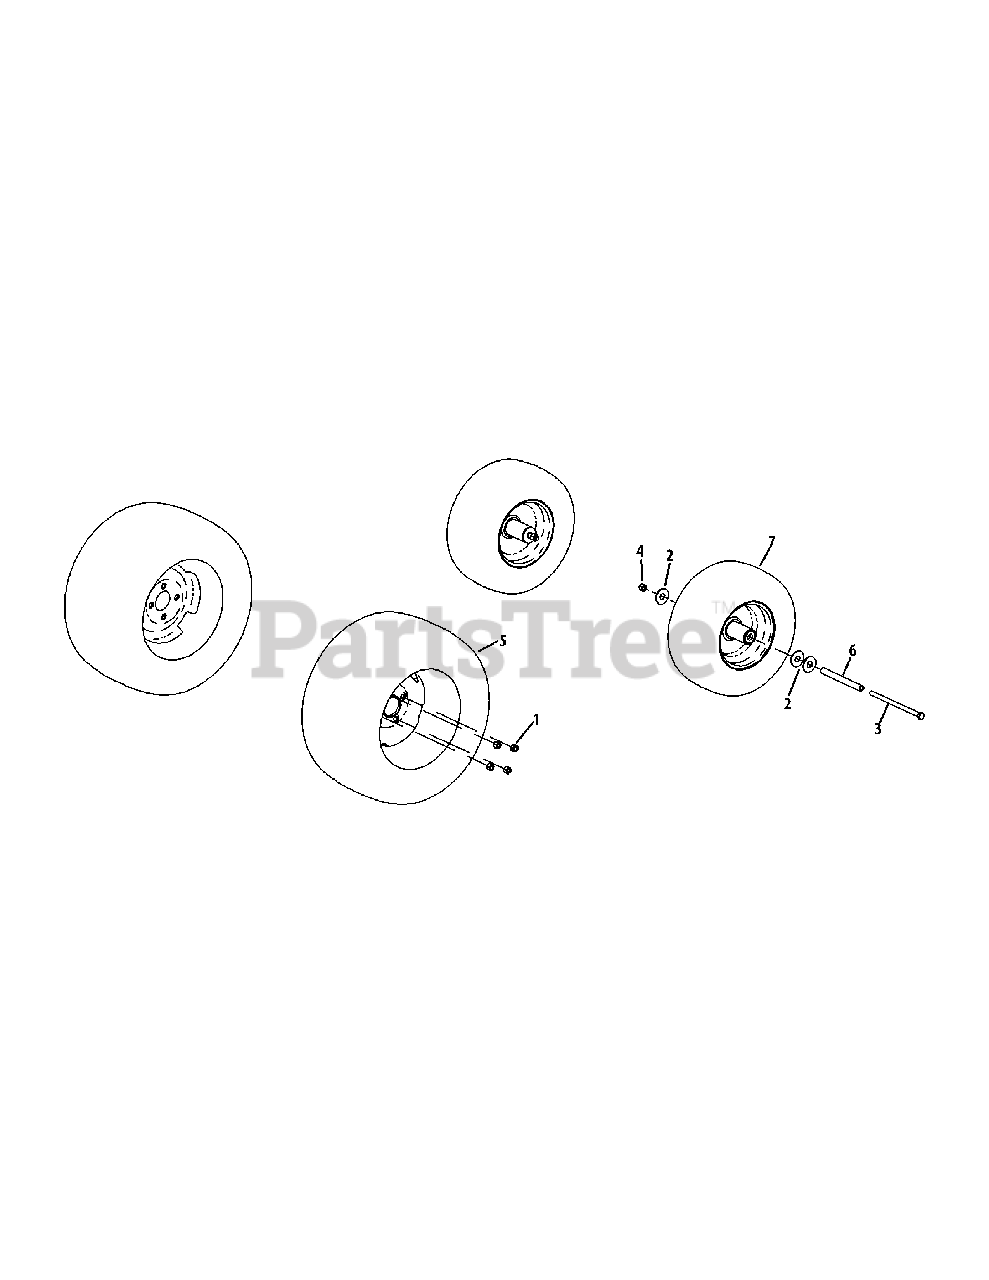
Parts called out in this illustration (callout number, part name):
1	Lug Nut, 1/2-20
2	Washer, .781 x 2.00 x .105
3	Hex Screw, 1/2-20 x 9.50
4	Nut, 1/2-20, Lock
5	Wheel Assembly, 24 x 12.00-12
5	Tire, 24 x 12.00-12, Turf Master
6	Spacer, .51 x .75 x 7.49
7	Front Wheel Assembly, 16 x 6.50-8
7	Front Caster Tire Only 16 X 6.5-8
